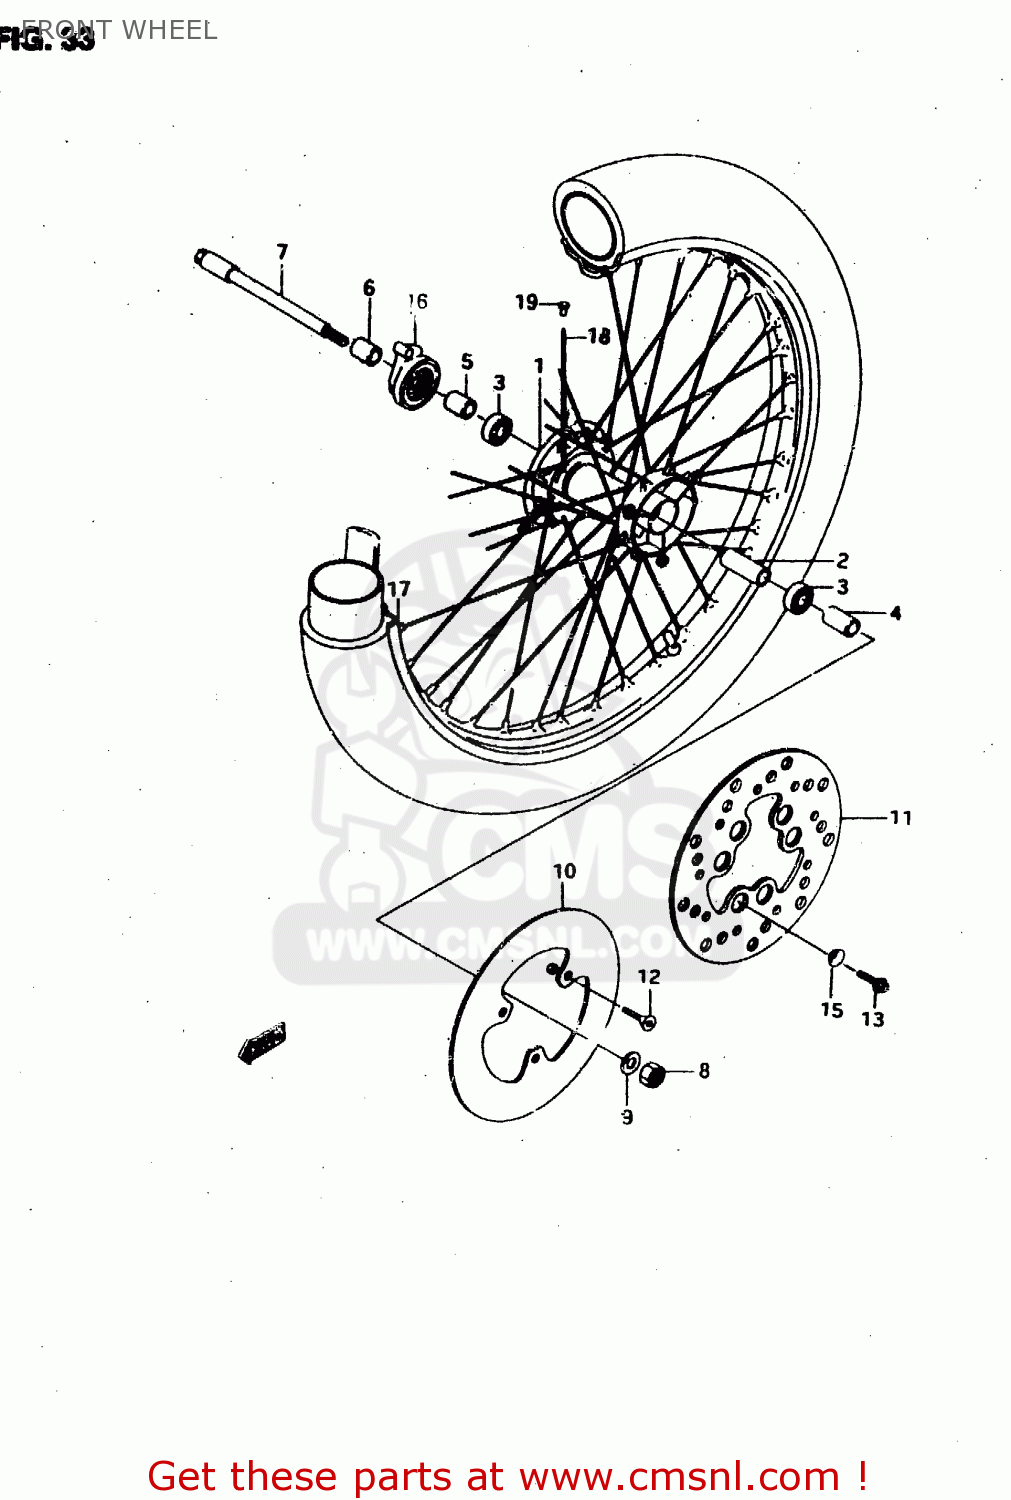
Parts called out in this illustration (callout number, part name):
1	HUB, FRONT WHEEL
2	SPACER, FRONT HUB
3	BEARING
4	SPACER (20X12.2X29)
5	SPACER (20X12.2X13.5)
6	SPACER (20X12.2X9.5)
7	AXLE, FRONT
8	NUT
9	WASHER
10	DISC, FRONT BRAKE
11	DISC, FRONT BR
12	BOLT
13	BOLT
14	NUT
15	WASHER
16	GEAR,SPEEDOMET
17	RIM, FRONT WHE
18	SPOKE
19	NIPPLE
